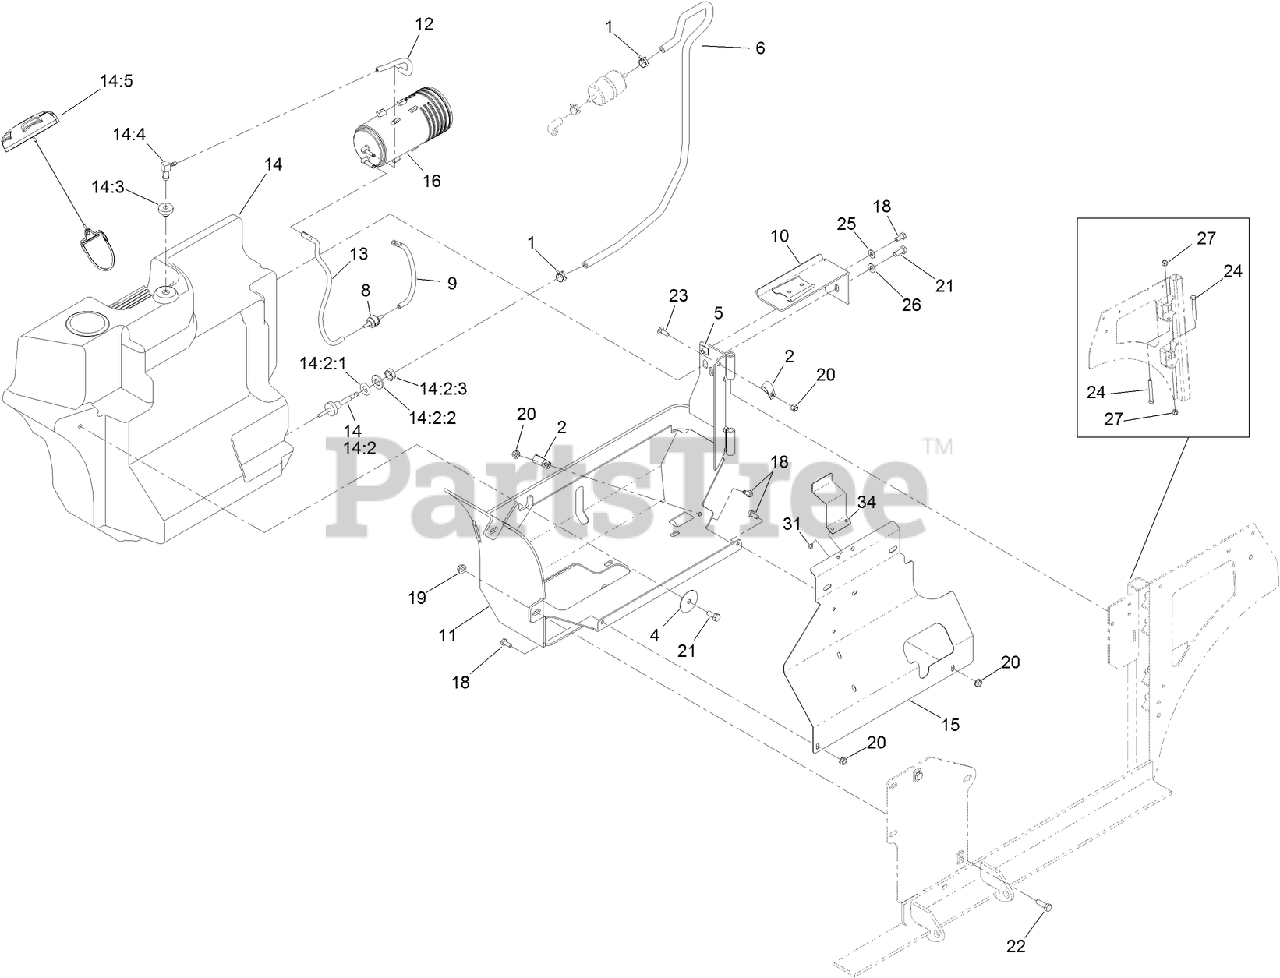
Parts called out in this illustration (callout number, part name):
1	CLAMP-HOSE
2	CLIP-LOOM
4	WASHER
6	HOSE-FUEL
8	VALVE-CHECK, VACUUM
9	HOSE-VENT, FORMED
10	CANISTER BRACKET ASM
11	TANK FRAME ASM
12	HOSE-VENT, FORMED
13	HOSE-VENT, FORMED
14	FUEL TANK ASM
14:2	FITTING-FUEL, BULKHEAD
14:2:1	O-Ring
14:2:2	WASHER-FLAT
14:2:3	NUT-JAM
14:3	BUSHING
14:4	FITTING-90 DEG
14:5	CAP-FUEL, RATCHETING
15	PANEL-TANK SHIELD
16	CANISTER-CARBON, 800CC
18	SCREW-HH
19	NUT-HF
20	NUT-HF
21	SCREW-HH
22	SCREW-HH
23	BOLT-CARR
24	SCREW-HH
25	WASHER-FLAT
26	WASHER-PLAIN
27	NUT-LOCK, NI
31	RIVET-POP
34	BRACKET-SHIELD, TANK
